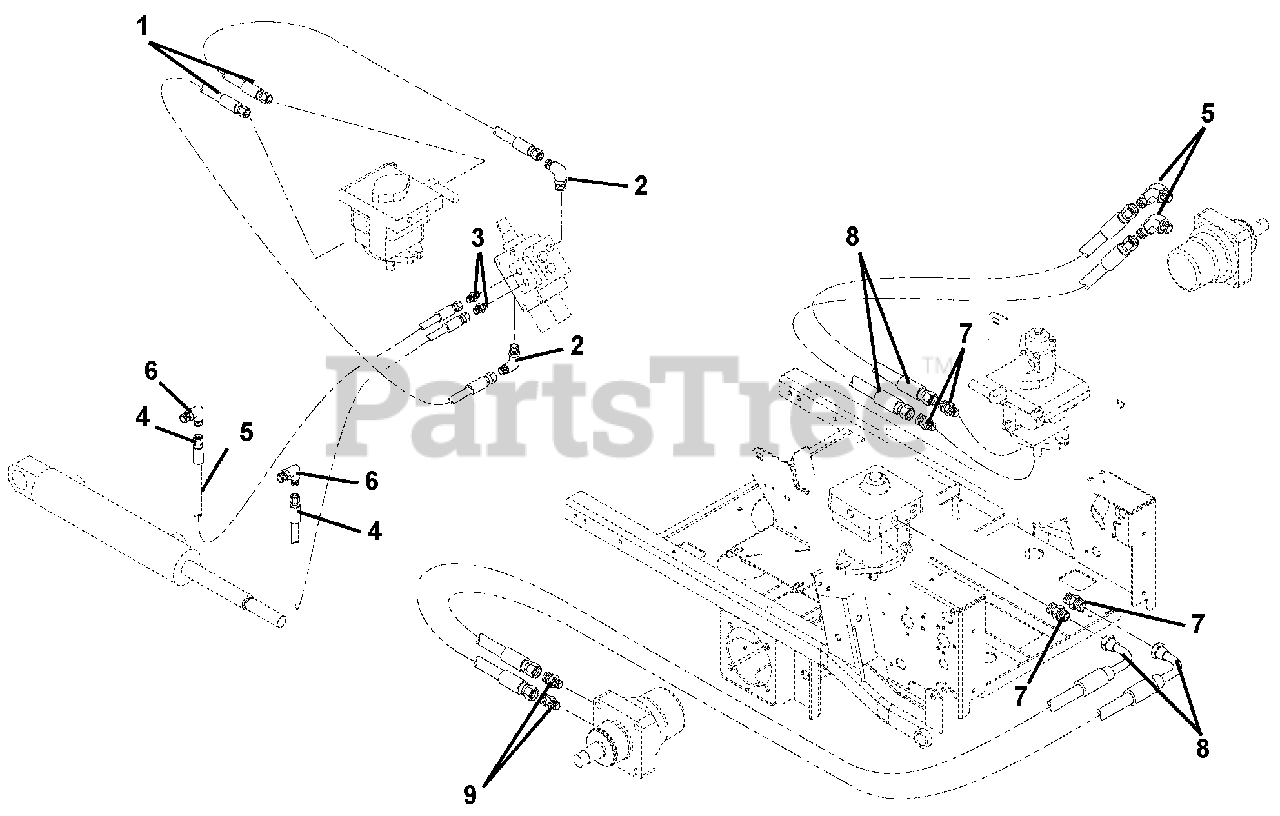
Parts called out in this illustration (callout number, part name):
1	Hose, Hydraulic (045, 046, 047, 052, 066, 067, 068, 071, 084, 085, 086, 091, 104, 106, 107, 108)
2	Hydraulic, Fitting Elbow (045, 046, 047, 052, 066, 067, 068, 071, 084, 085, 086, 091, 104, 106,
3	Adapter (4-6F5OLO) (045, 046, 047, 052, 066, 067, 068, 071, 084, 085, 086, 091, 104, 106, 107,
4	Hose, Hydraulic (045, 046, 047, 052, 066, 067, 068, 071, 084, 085, 086, 091, 104, 106, 107, 108)
5	Fitting, Hydraulic (8-10 V5OLO)
6	Fitting, Hydraulic (4 C5OLO) (045, 046, 047, 052, 066, 067, 068, 071, 084, 085, 086, 091, 104,
7	Adapter, Face Seal 8 x 8 .50 O-Ring
8	Hose, Hydraulic .50
9	Adapter, Hydraulic Steel (M10 O-M8F)
